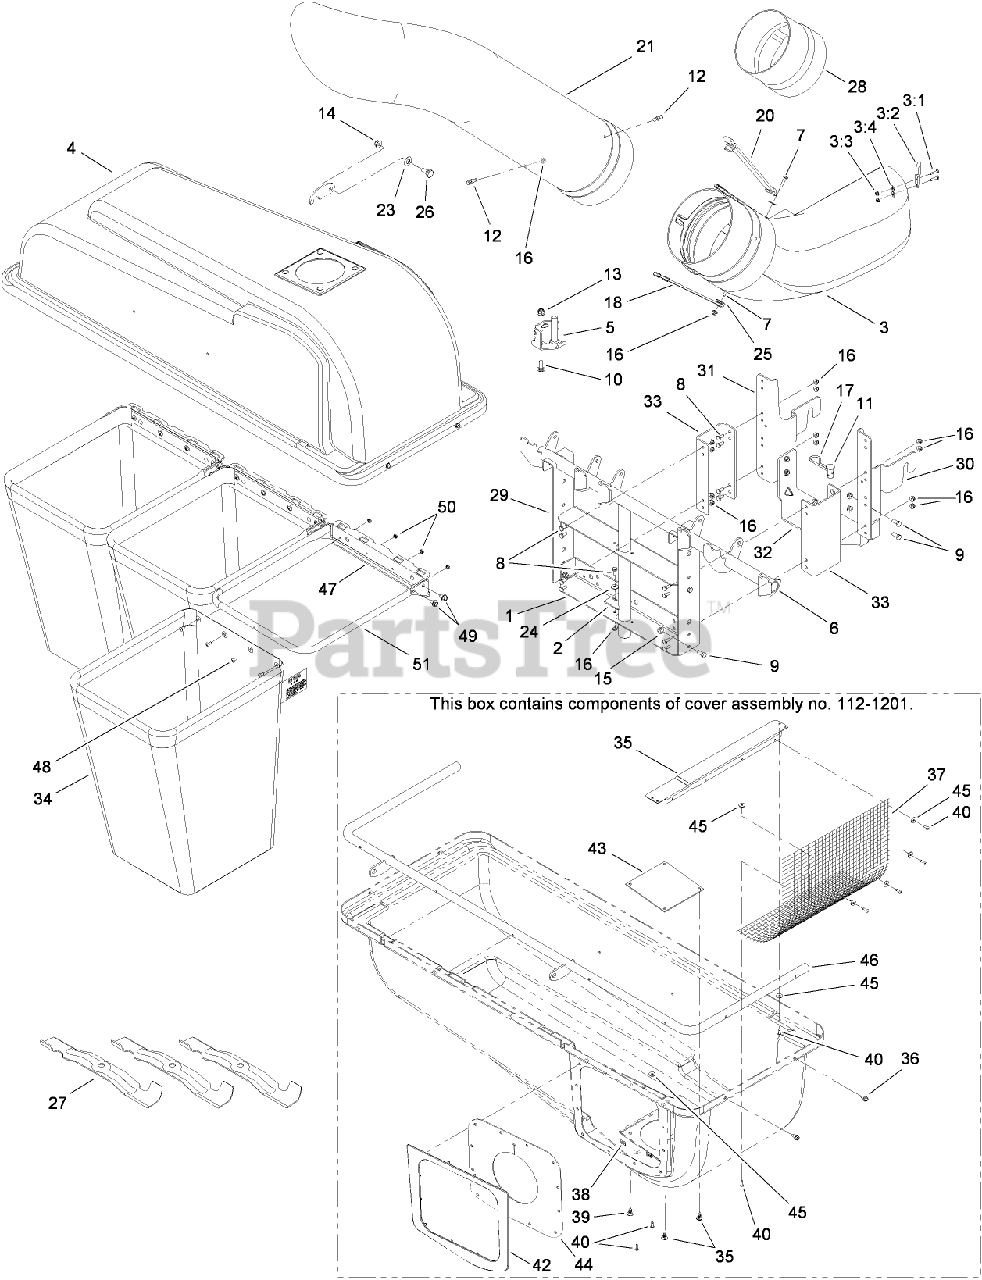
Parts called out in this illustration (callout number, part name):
1	BRACKET-SUPPORT, CATCHER
2	BRACKET-TUBING, ADAPTER
3	DISCHARGE CHUTE ASM
3:1	SCREW-HEX
3:2	ROD-MOUNT, BAG
3:3	NUT-LOCK, FLANGE
3:4	WASHER-FLAT
4	COVER ASM
5	CHUTE STOP BRACKET ASM
6	CATCHER SUPPORT ASM
7	SCREW-HH
8	SCREW-HH
9	SCREW-HH
10	BOLT-CARRIAGE
11	PIN-CLEVIS
12	PIN-CATCHER, GRASS
13	NUT-LOCK, HEX
14	NUT-LOCK, FLANGE
15	NUT-LOCK, FLANGE
16	NUT-LOCK, FLANGE
17	CLIP-HAIRPIN
18	STRAP-CHUTE
20	STRAP-CHUTE
21	TUBE-ELBOW, CATCHER
23	WASHER-BELL
24	WASHER-SPRING
25	WASHER-FLAT
26	BOLT-SHOULDER
27	BLADE-EXTRA HI LIFT (18.50 INCH)
28	TUBE-EXTENSION
29	BRACKET-SUPPORT
30	BRACKET-CATCHER, RH
31	BRACKET-CATCHER, LH
32	BRACKET-CROSS, SUPPORT
33	BRACKET-CATCHER
34	BAG-GRASS
35	BRACKET-MOUNTING, SCREEN
36	SCREW-HWH
37	SCREEN
38	NUT-PUSH
39	CLIP-RATCHET
40	RIVET-POP
42	SEAL-RETAINER
43	PLATE-PLASTIC
44	SEAL-BAG, GRASS
45	WASHER-FLAT
46	BRACKET-HINGE
47	BRACKET-HANGER, BAG
48	SCREW-TRUSS, MACHINE
49	SCREW-HWH
50	NUT-SEMS
51	FRAME-BAG, CATCHER
